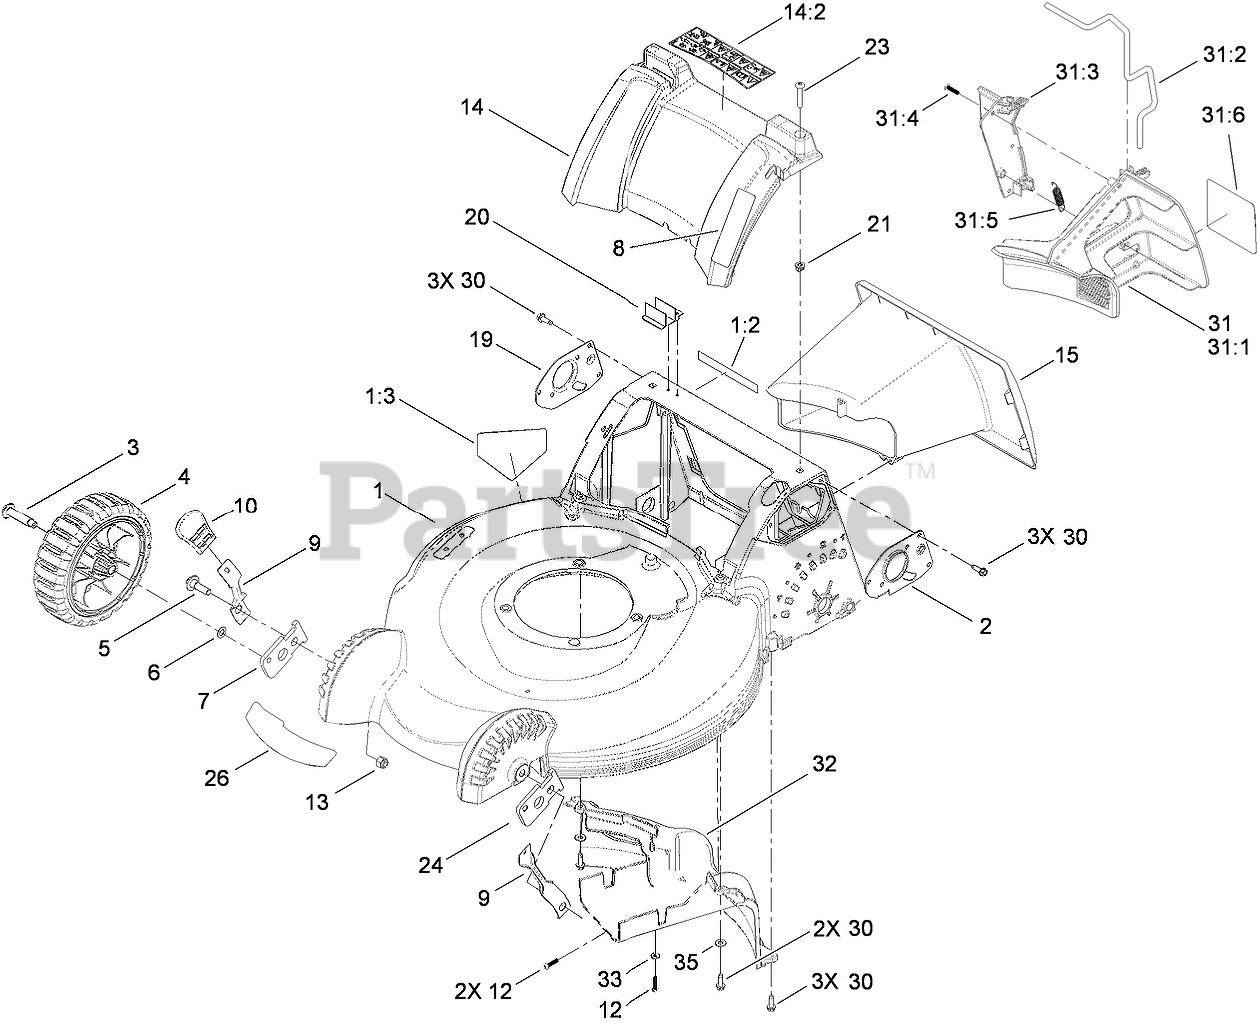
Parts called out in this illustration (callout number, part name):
1	HOUSING ASM
1:2	DECAL-SAFETY
1:3	DECAL-DANGER
2	MOUNT-HANDLE, LH
3	BOLT-SHOULDER
4	8 INCH WHEEL ASM
5	BOLT-SHOULDER
6	WASHER
7	ARM-PIVOT, RH
8	DECAL-QUICK STOW
9	ARM-SPRING, FRONT
10	KNOB-HOC
12	SCREW-PLASTITE
13	NUT-LOCK, NI
14	REAR COVER ASM
14:2	DECAL-WARNING
15	TUNNEL
19	MOUNT-HANDLE, RH
20	MODULE-SWITCH
21	NUT-CLIP
23	SCREW-PTH
24	ARM-PIVOT, LH
26	DECAL-SUPER BAGGER
30	SCREW-HWHTF
31	MULCH PLUG ASM
31:1	PLUG-MULCH, LH
31:2	LATCH-PLUG, MULCH
31:3	PLUG-MULCH, RH
31:4	SCREW-PLASTITE
31:5	SPRING-EXTENSION
31:6	DECAL-PLUG, MULCH
32	BAFFLE-REAR
33	WASHER-FLAT
35	WASHER-FLAT
